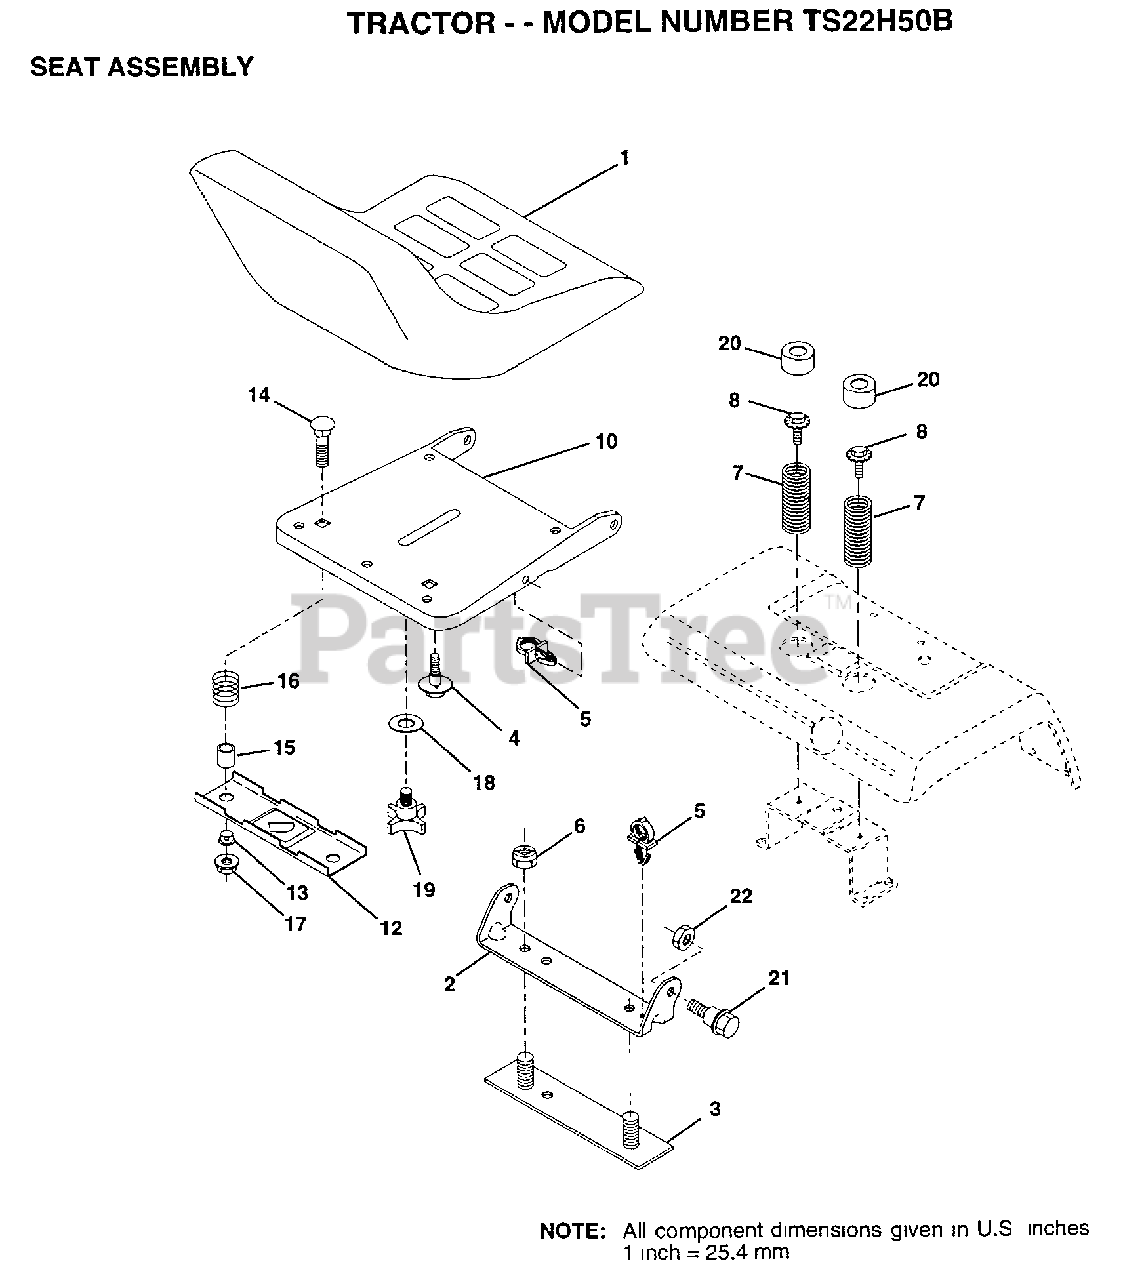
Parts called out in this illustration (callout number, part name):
1	Seat
2	BRACKET PVT SEAT
3	STRAP ASM FENDER
4	"BOLT,SHOULDER"
5	CLIP.PUSH-IN.HING
7	SPRING COMPRESSIO
8	BOLT.5/16-18.UNC
12	BRKT SWITCH
13	BUSHING
15	SPACER SPLIT
16	SPRING COMPRESSED
18	WASHER
19	"KNOB 1/2"" YT"
20	CAP SPRING
21	"BOLT,SHOULDER"
